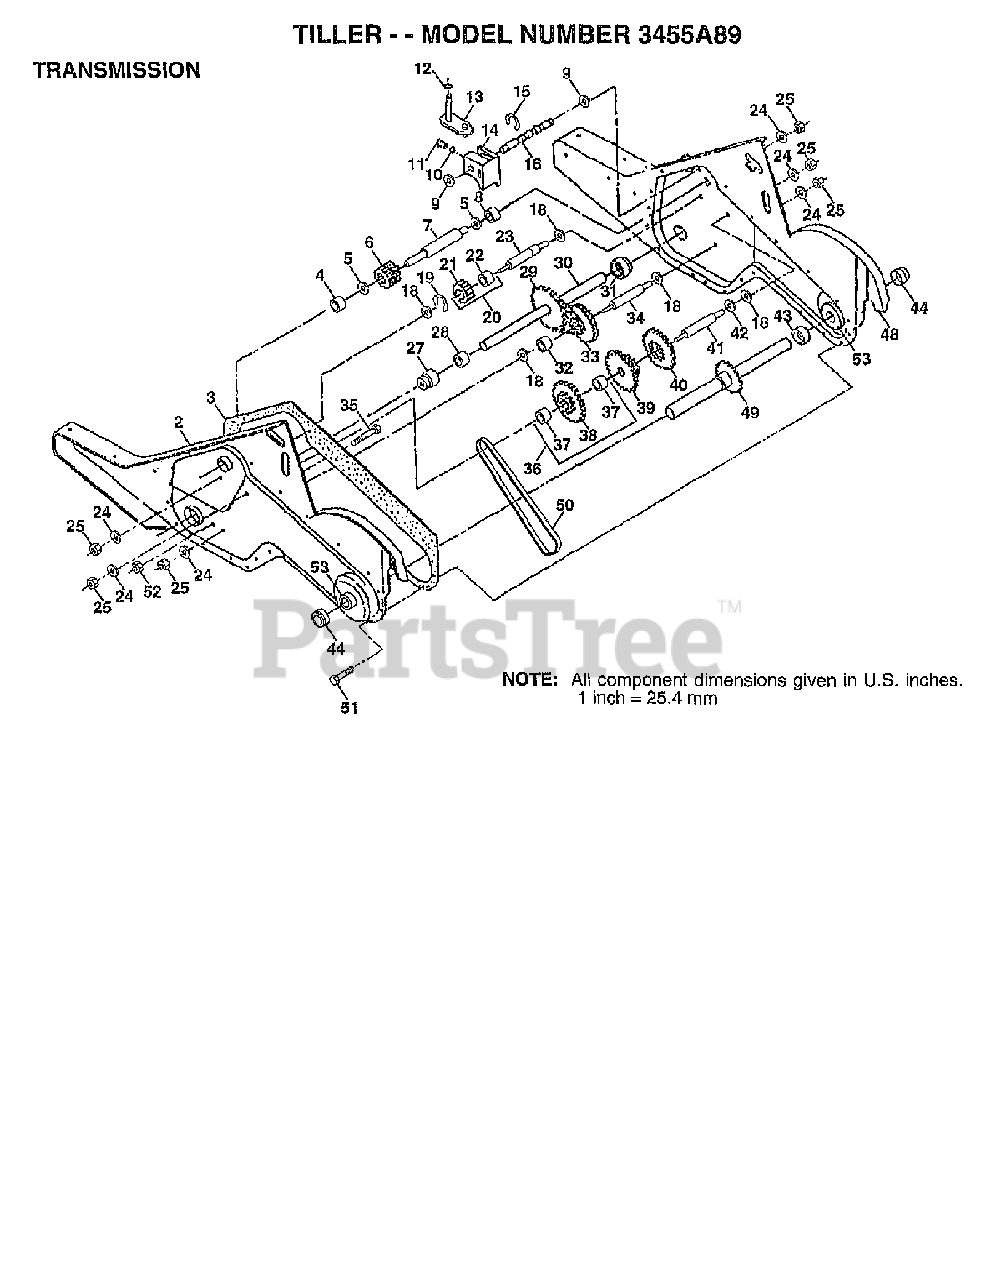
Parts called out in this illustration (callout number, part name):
1	TRANSMISSION ASSY
2	GEARCASE
3	Gear Case Gasket, CRT/DRT Tiller
4	NEEDLE BRNG LT
5	THRUST WASHER
6	GEAR.PINION.INPUT
7	SHAFT.INPUT."D"".TILLER
9	WASHER, SEAL
10	BALL, STEEL
11	SPRING-SHIFT CRT
12	O-RING TI
13	SHIFT ARM
14	SHIFT FORK TI
15	KLIP RING
16	SHAFT.SHIFTER.TILLER
19	KLIP RING
20	GEAR ASSY CRT
21	GEAR-REV IDLR CRT
22	NEEDLE BEARING TI
23	SHAFT CRT
24	LOCKWASHER
25	NUT.ASF.HEX.7/16
27	BEARING, SHAFT LH CRT
29	CHAIN CRT
30	GROUND SHAFT ASS'Y
31	BEARING, SHAFT RH CRT
32	SPACER TI
33	SPRCKT 8 GEAR CRT
34	SHAFT.SECONDARY.REDUCTION.CRT
35	SCRW WHIZ LOK CRT
36	SPROCKET.ASM.W/BEARING.TILLER
37	BEARING
39	GEAR TI
41	SHAFT.REDUCTION.TILLER
42	BRNG RACE T
43	SPACER TI
44	SEAL ASM, OIL
48	GEARCASE
49	SHAFT ASSY TI
50	CHAIN.TILLER
